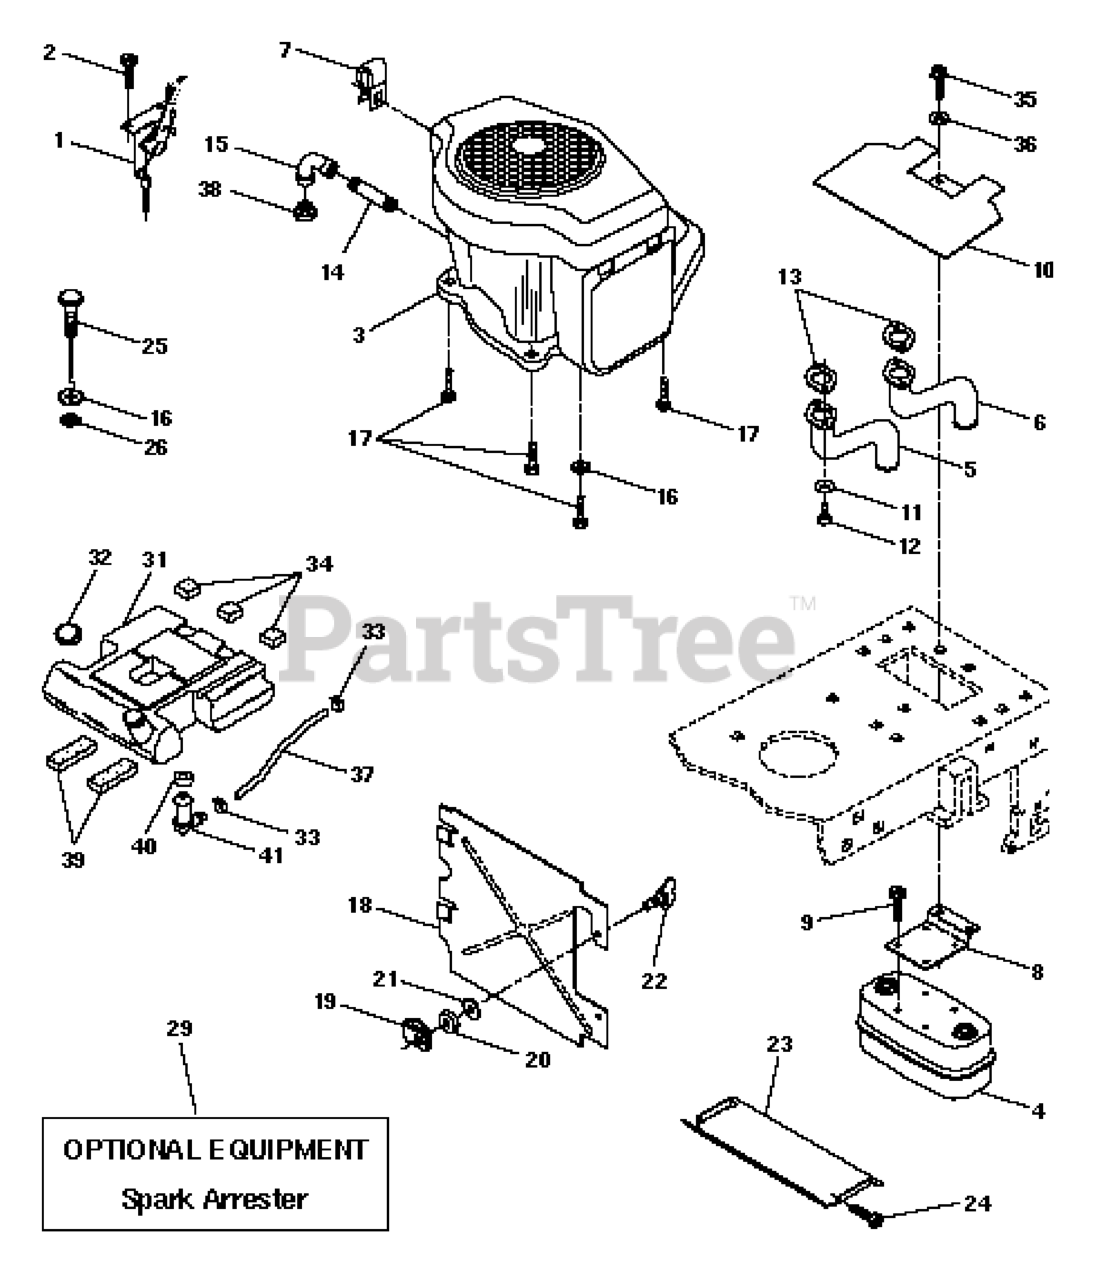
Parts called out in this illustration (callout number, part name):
1	THROTTLE CONTROL
2	SCREW LT
4	MUFFLER
5	MANIFOLD TUBE LH
6	MANIFOLD TUBE RH
8	BRACKET MUFFLER
9	SCREW ST
10	HEAT SHIELD
11	WASHER.LOCK.HVY.HLCL.SPR.5/16
12	Bolt, Fin Hex 1/4-20 x 3/4
13	Muffler Gasket
14	Nipple Pipe 3/8 Npt X 4-1/2"
15	ELBOW
16	LOCKWASHER
17	SCREW LT
18	HEAT SHIELD
19	RECEPTACLE LT
20	RETAINER LT
21	SNAP BUSHING T
22	STUD 1/4 TURN
23	HEAT SHIELD
25	CHOKE CONTROL
26	NUT
29	KIT.SPARK ARRESTOR 794945 B&S
31	FUEL TANK
32	FUEL CAP
33	HOSE CLAMP
34	PAD-SPACER LT
35	SCREW.THDROL.5/16-18X3/4.TTY
36	WASHER
37	FUEL LINE 54"
38	Plug Oil Drain
39	PAD IDLER TI
40	BUSHING OUTLET T
41	STEM FUEL TANK
